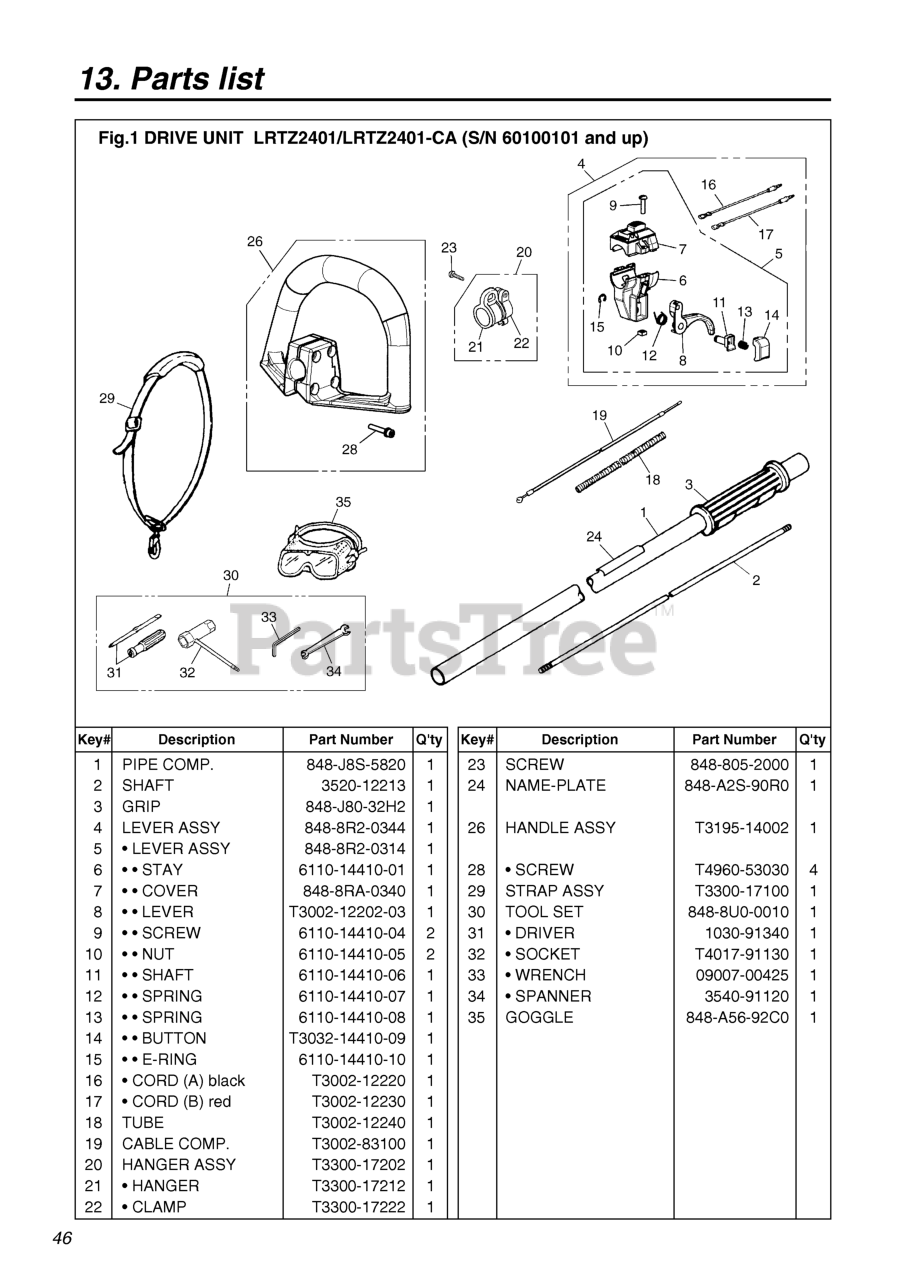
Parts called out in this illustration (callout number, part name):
1	PIPE COMP.
2	SHAFT (RPLS -12212)
3	GRIP
4	LEVER ASSY
5	LEVER
7	COVER COMP. (RP. 6110-14410-02)
8	FLEX, TRIGGER
16	CORD (A), BLACK
17	CORD (B), RED
18	TUBE (RPLS 4900-72141)
19	CABLE (RPLS 5580-83100)
20	HANGER COMP.
23	SCREW
24	NAMEPLATE
26	HANDLE ASSY. (REPLACES -14001)
28	SCREW
29	STRAP ASSY.
30	TOOL-SET
31	SCREWDRIVER
33	WRENCH (TOOL)
34	SPANNER, 8 x 10 (RP 090100810)
35	GOGGLE
